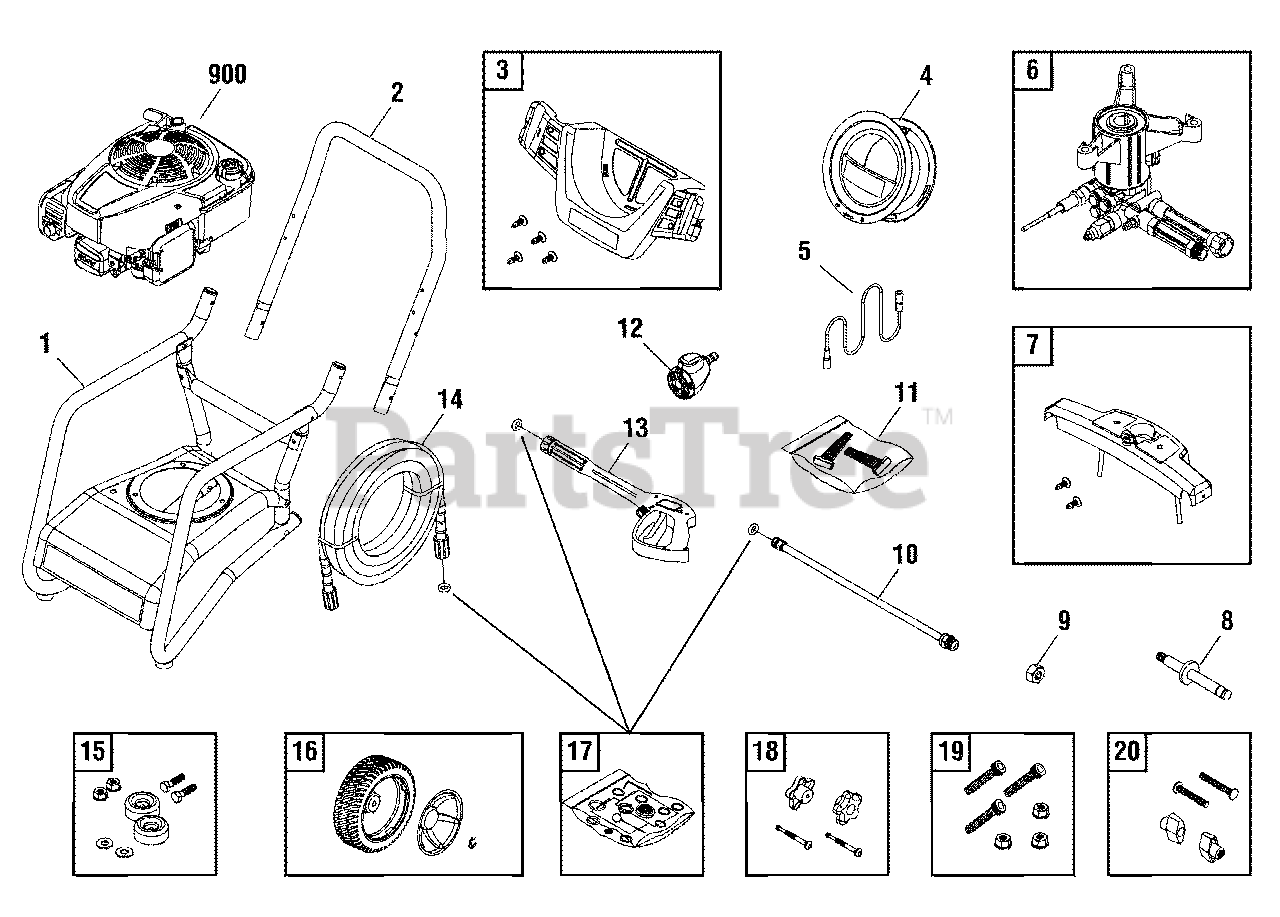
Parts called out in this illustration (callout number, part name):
1	BASE
9	NUT
10	EXTENSION-QC
13	GUN
15	MOUNT-VIBRATION
17	KIT-0-RING
19	KIT-HARDWARE PUMP MOUNTING
